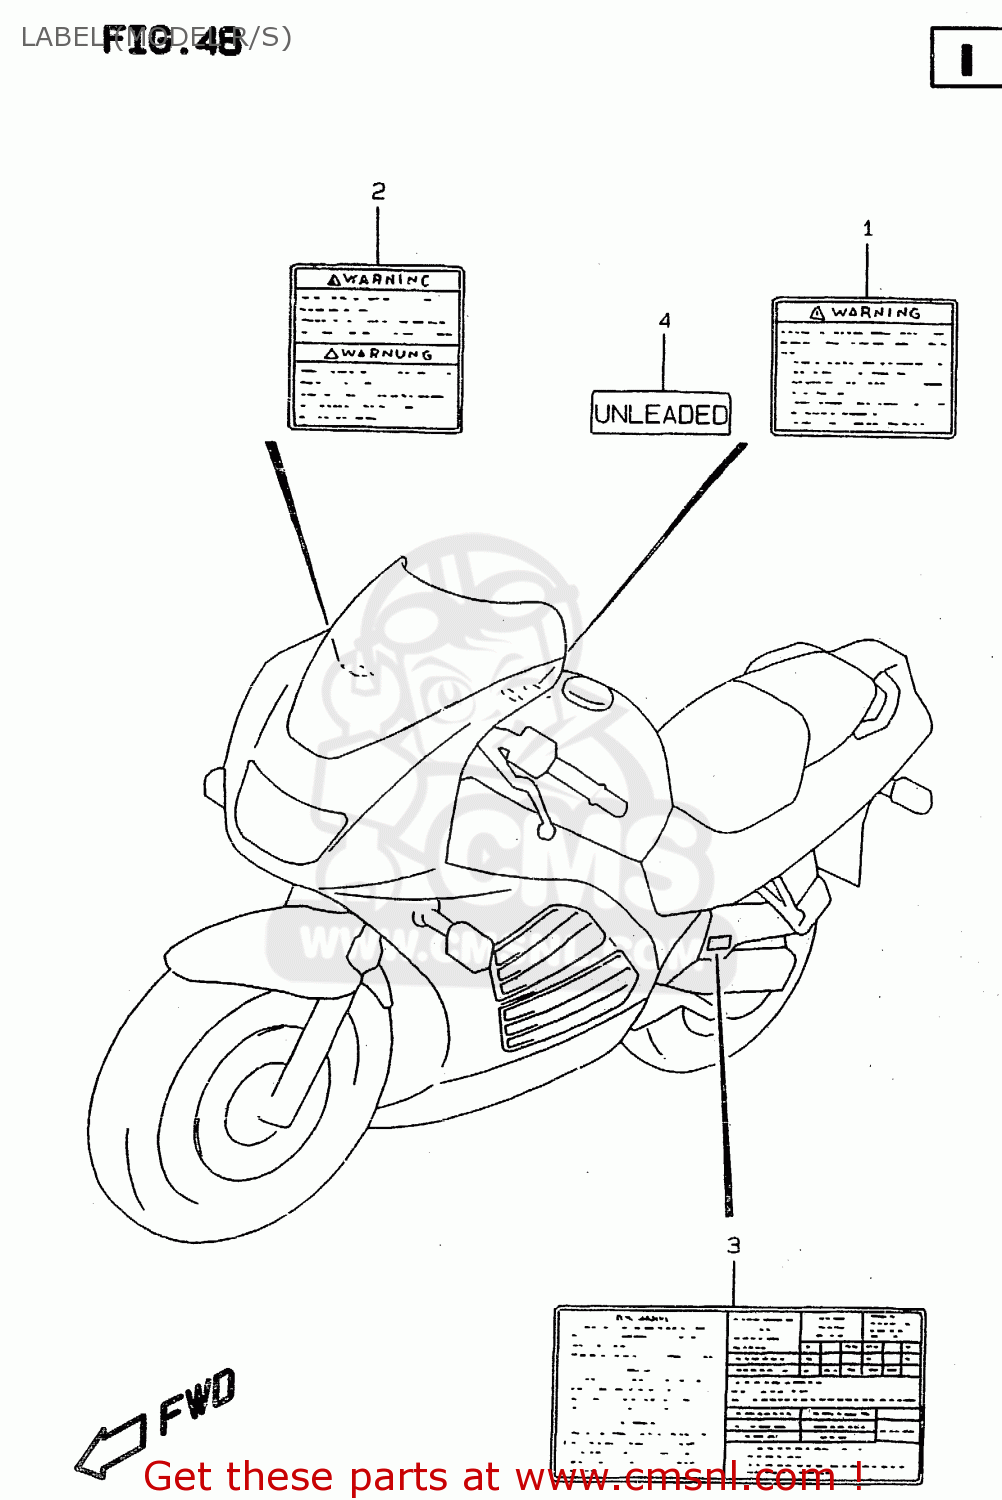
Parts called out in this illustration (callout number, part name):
1	LABEL, WARNING SAFETY
2	LABEL,WARNING STEERING
3	LABEL (TIRE INFORMATION)
4	LABEL,CAUTION
5	MANUAL, OWNER'S
